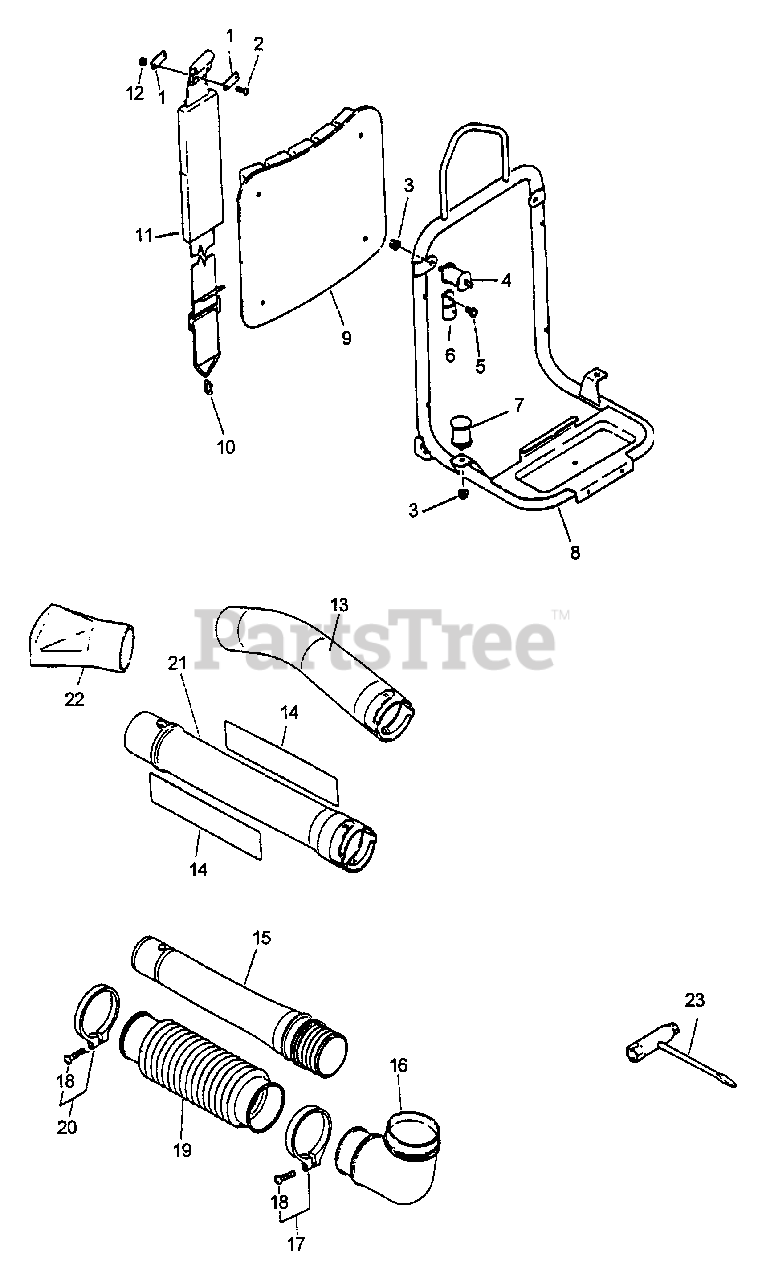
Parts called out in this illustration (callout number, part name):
2	SCREW 5×10
3	NUT, FLANGE M6
5	SCREW 5×10
6	BRACKET, CUSHION
8	FRAME, BACKPACK
9	CUSHION, BACKPACK
10	RING, HARNESS
11	HARNESS ASSY, BACKPACK
12	NUT, LOCK M5
13	TUBE, BLOWER - CURVED
14	LABEL - ECHO
15	TUBE, BLOWER - SWIVEL
17	CLAMP KIT
18	SCREW 5×30
19	TUBE, FLEXIBLE
20	CLAMP KIT
21	BLOWER TUBE KIT - STRAIGHT
22	NOZZLE - FAN HEAD
23	T-WRENCH 10×19 MM
